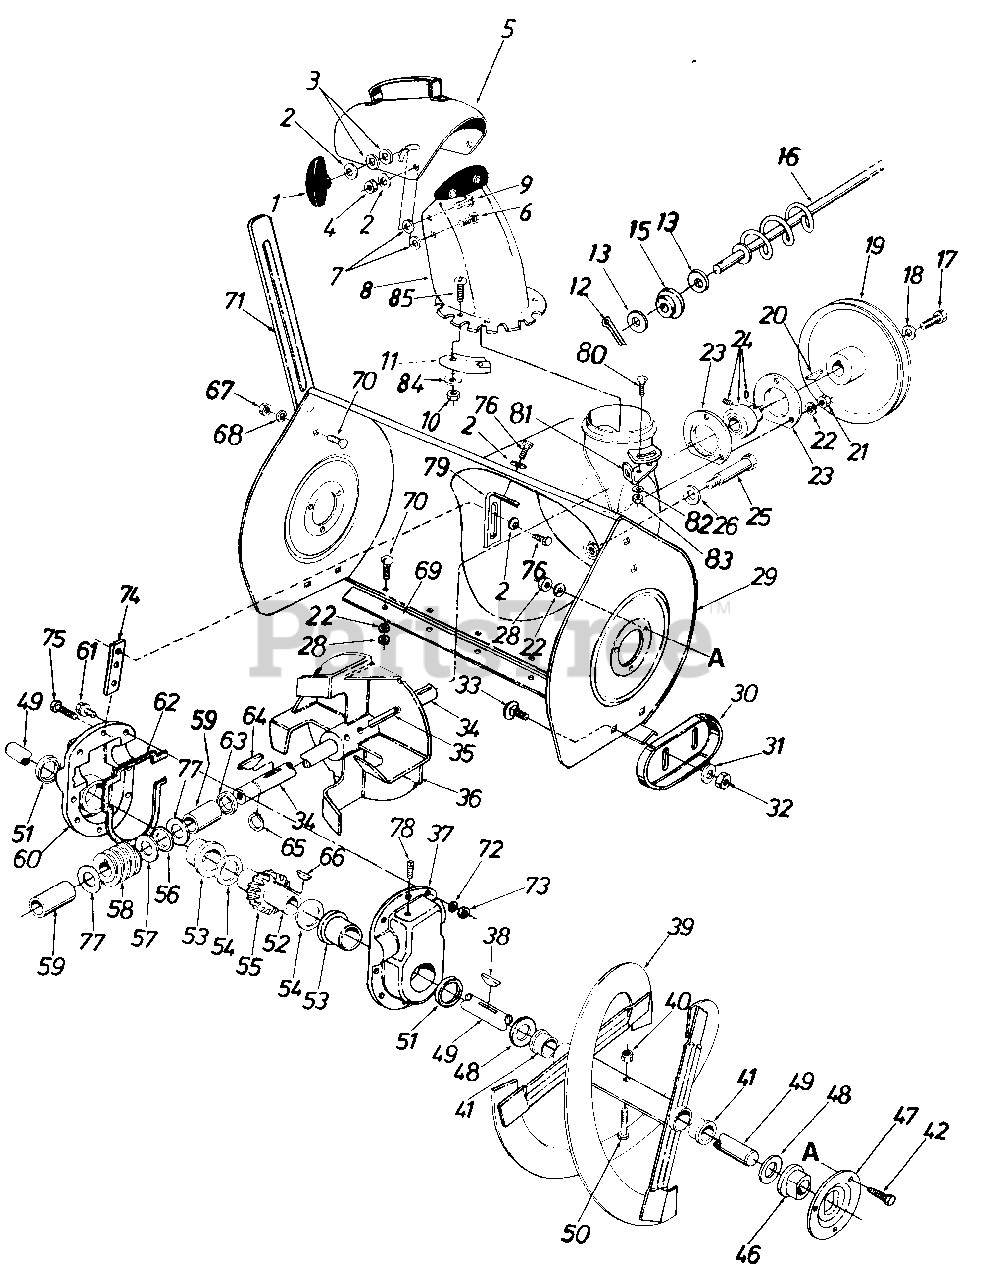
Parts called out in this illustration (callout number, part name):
1	Hand Knob Ass'y.
2	Bell-Wash. .345 I.D. x .88 O.D. x .060
3	Fl. Wash. .312 I.D. x 1.125 O.D. x .125
4	Hex Cent. L-Nut 5/16-18 Thd.
5	Top Chute Ass'y.
6	Carr. Bolt 5/16-18 x .62" Lg.
7	Fl-Wash. .53 I.D. x 1.25 O.D. x .1 00
8	Chute Ass'y.
9	Carr. Bolt 5/16-18 x 1.00" Lg.
10	Hex Cent. L-Nut '/2-20 Thd.
11	Chute Flange Keeper Ass'y.
12	Cotter Pin
13	Fl-Wash. .385" I.D. x .62" O.D.
15	Bushing
16	Chute Crank Ass'y.
17	Hex L-Scr. 5/16-18 x .88" Lg.
18	Bell-Wash. .345 I.D. x .88 O.D. x .060
19	V-Pulley .875 I.D. x 10.12 O.D.
20	#9 Hi-Pro Key 3/16 x 3/4" Dia.
21	Hex Nut 5/16-18 Thd.
22	L-Wash. 5/16" Scr.
23	Bearing Hsg. Self Aligning Brg.
24	Self Aligning Brg. .875 I.D.
25	Stud 3/8-16 x 2.75" Lg.
26	Bell-Wash. .400 I.D. x .88 O.D. x .060
28	Hex Nut 5/16-18 Thd.
29	Blower Hsg. Ass'y.
30	Slide Shoe
31	Bell-Wash. .400 I.D. x .88 O.D. x .060
32	Hex Jam Nut 3/8-16 Thd.
33	Carr. Bolt 3/8-16 x .62" Lg.
34	Blower Axle
35	Spring Pin Spiral 5/16" Dia. x 1.75" Lg.
38	#91 Woodruff Key 1/4" x 3/4" Dia.
39	33" Spiral Ass'y. L.H.
40	Hex Ins. L-Nut 5/16-18 Thd.
41	Plastic Bushing
42	Hex Sems Scr. 5/16-18 x .75" Lg.
46	Flange Brg. w/Flats 1.0" I.D.
47	Bearing Hsg. Spiral Hsg.
48	Fl-Wash. 1.06 I.D. x 1.75" O.D. x .100
49	Spiral Axle 33"
50	Hex Bolt 5/16-18 x 1.75" Lg.
51	Oil Seal 1.50" I.D.
52	Worm Gear Shaft
53	Flange Brg. 1.503 I.D.
54	Fl-Wash. 1.50 I.D. x 2.00 O.D. x .030
55	Double Threaded Worm Gear
56	Thrust Brg. .88 I.D. x 1.44 O.D. x .078
57	Fl-Wash. .88 I.D. x 1.40 O.D. x .1 50
58	Double Threaded Worm L.H.
59	Sleeve Brg. .875 I.D.
60	Complete Gear Hsg. Half R.H.
61	Hex Scr. 5/16-18 x 1.00" Lg.
62	Gasket
63	Oil Seal .875" I.D.
64	#9 Hi-Pro Key 3/16 x 3/4" Dia.
65	Snap Ring for .875" Dia. Shaft
66	#91 Woodruff Key 1/4 X 3/4" Dia.
67	Hex Nut 5/16-18 Thd.
68	L-Wash. 5/16" Scr.
70	Carr. Bolt 5/16-18 x .62" Lg.
71	Drift Cutter
72	Wave Wash. 5/16" Scr.
73	Hex Ins. L-Nut 5/16-18 Thd.
74	Gear Hsg. Support Brkt.
75	Hex Scr. 5/16-18 x 1.25" Lg.
76	Hex Wash. Hd. Self-Tap Scr. 5/16-18 x .75" Lg.
77	Fl-Wash. .88 I.D. x 1.40 O.D. x . 150
78	Filler Plug
80	Carr. Bolt 5/16-18 x .75" Lg.
82	Bell-Wash. .345 I.D. x .88" O.D.
83	Hex Nut 5/16-18 Thd.
84	Fl-Wash. 1/4" I.D.
85	Truss Mach. Scr. 1/4-20 x .75" Lg.
